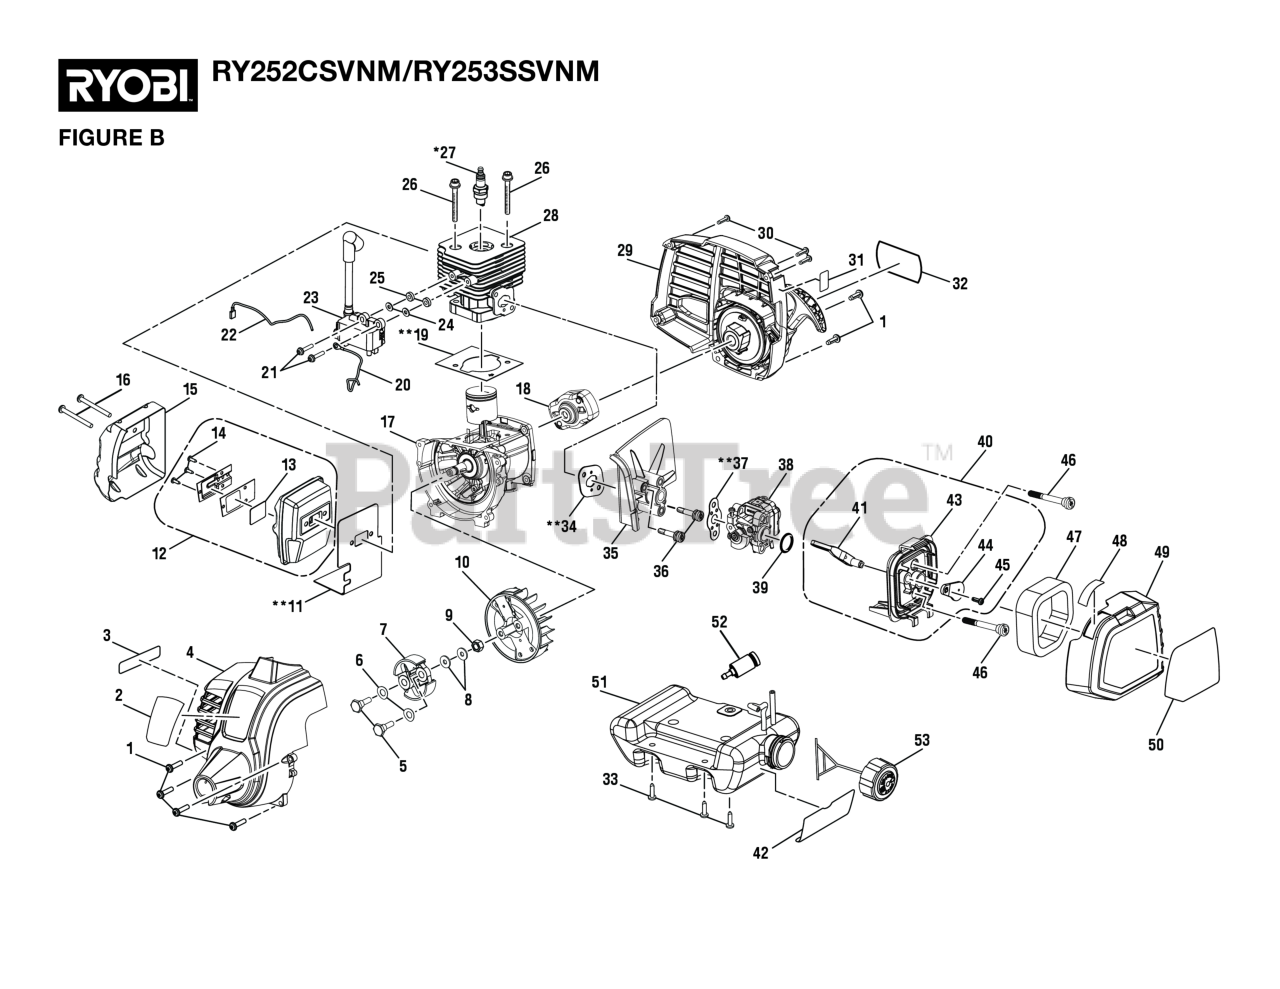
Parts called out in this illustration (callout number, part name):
1	Cap Screw w/Washer (M5 x 16 mm, T25 Torx Soc. Hd.)
2	Logo Label (Front)
3	Warning Label (Combustion)
4	Front Housing Assembly w/ Labels
5	Clutch Shoulder Bolt (M6 x 22.5 mm, Hex Hd.)
6	Washer (Curved)
7	Clutch Assembly
8	Washer (ID6 x OD15 x 1.2t)
9	Flange Nut (M8, Flywheel)
11	Muffler Gasket
12	Muffler Assembly
13	SCREEN
14	Screw (6-20 x 1/4 in., T20 Torx Pan Hd. S.T.)
15	HEAT SHIELD
16	Screw (M5 x 50 mm, Torx Slotted Recessed Pan Hd.)
17	Crankcase Assembly
18	Starter Cup
19	Gasket
20	Lead Wire Assembly, Red
21	Screw (M4 x 22 mm, T20 Torx Slotted Recessed Pan Hd.)
22	Lead Wire Assembly, Black
24	Flat Washer (OD10 x ID42 x 1t)
25	Phenolic Spacer (Ignition Module)
26	Screw (M5 x 22 mm, T25 Torx Soc. Hd.)
27	Spark Plug (Champion RCJ6Y)
29	Screw (M4 x 18 mm, T20 Torx Pan Hd. S.T.)
30	Screw (M4 x 20 mm, T20 Torx Pan Hd. S.T.)
31	Primer Bulb Location Label
32	Shoulder Screw (M4 x 14 mm, T25 Torx Truss Hd.
33	Shoulder Screw w/Washer (M4 x 14 mm, T25 Torx Truss Hd.)
34	Heat Dam Insulator
35	Screw (M5 x 30 mm, T25 Torx Pan Hd. S.T.)
36	Screw w/Washers (M5 x 30 mm, T25 Torx Pan Hd.)
37	Gasket
38	Carburetor Assembly
39	Carburetor O-Ring
40	Airbox Base Assembly
41	Compression Limiters
42	Fuel Mixture Label
43	Air Box Base
44	Screw (M4 x 12 mm, T20 Torx Pan Hd. S.T.)
45	Screw (M4 x 12 mm, Slotted Recessed Pan Hd.)
46	Screw (M5 x 45 mm, T20 Torx Truss Hd.)
47	Air Filter (Element)
48	Choke Position Label
49	Airbox Cover (Inc. Key Nos. 48 & 50)
50	Starting Instructions Label
51	Fuel Tank and Cap Assembly
52	Fuel Filter
53	Fuel Cap Assembly
